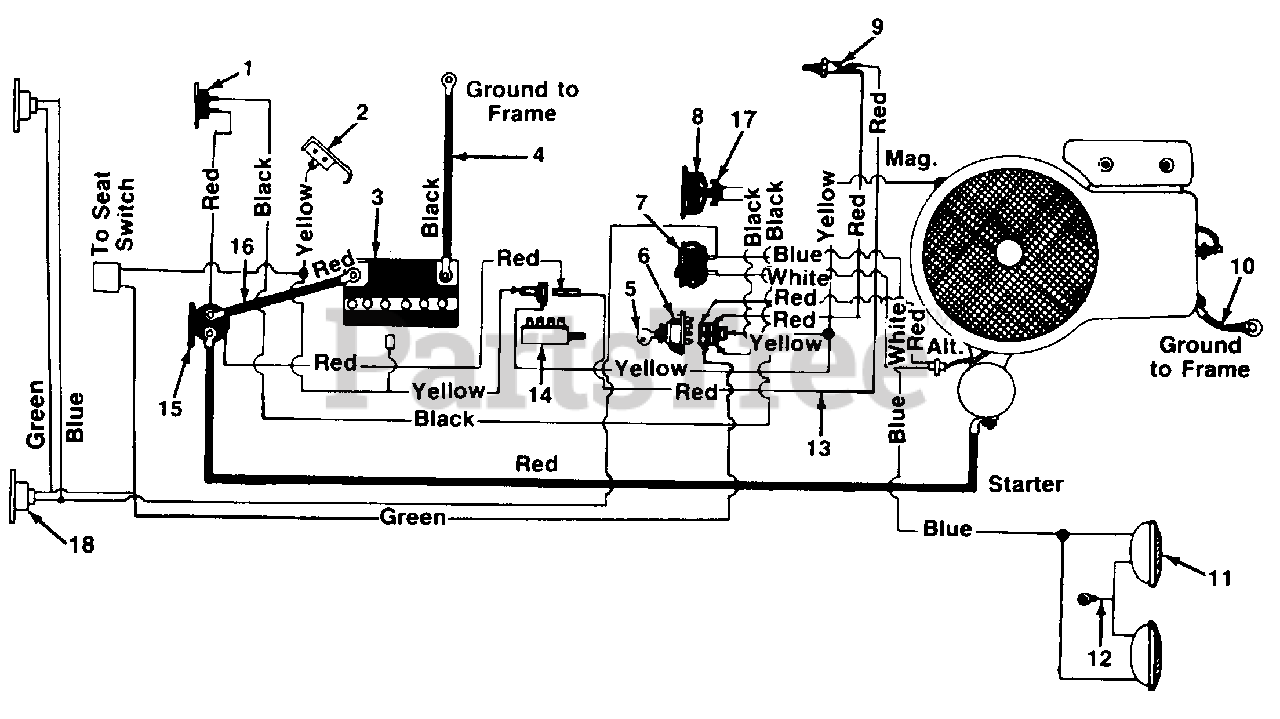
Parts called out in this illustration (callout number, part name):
1	Circuit Breaker
2	Spring Switch
3	12V-Battery
4	Grounding Wire 9.0" Lg.
5	Ignition Key
6	Ignition Switch
7	Headlight Switch
8	Ammeter
9	Safety Switch
10	Ground Wire 7.25" Lg.
11	Headlight
12	Ground Wire
13	Wire Harness
14	Safety Switch
15	Solenoid
16	Electric Wire w/Boot
17	Foam Strip
18	Taillight
